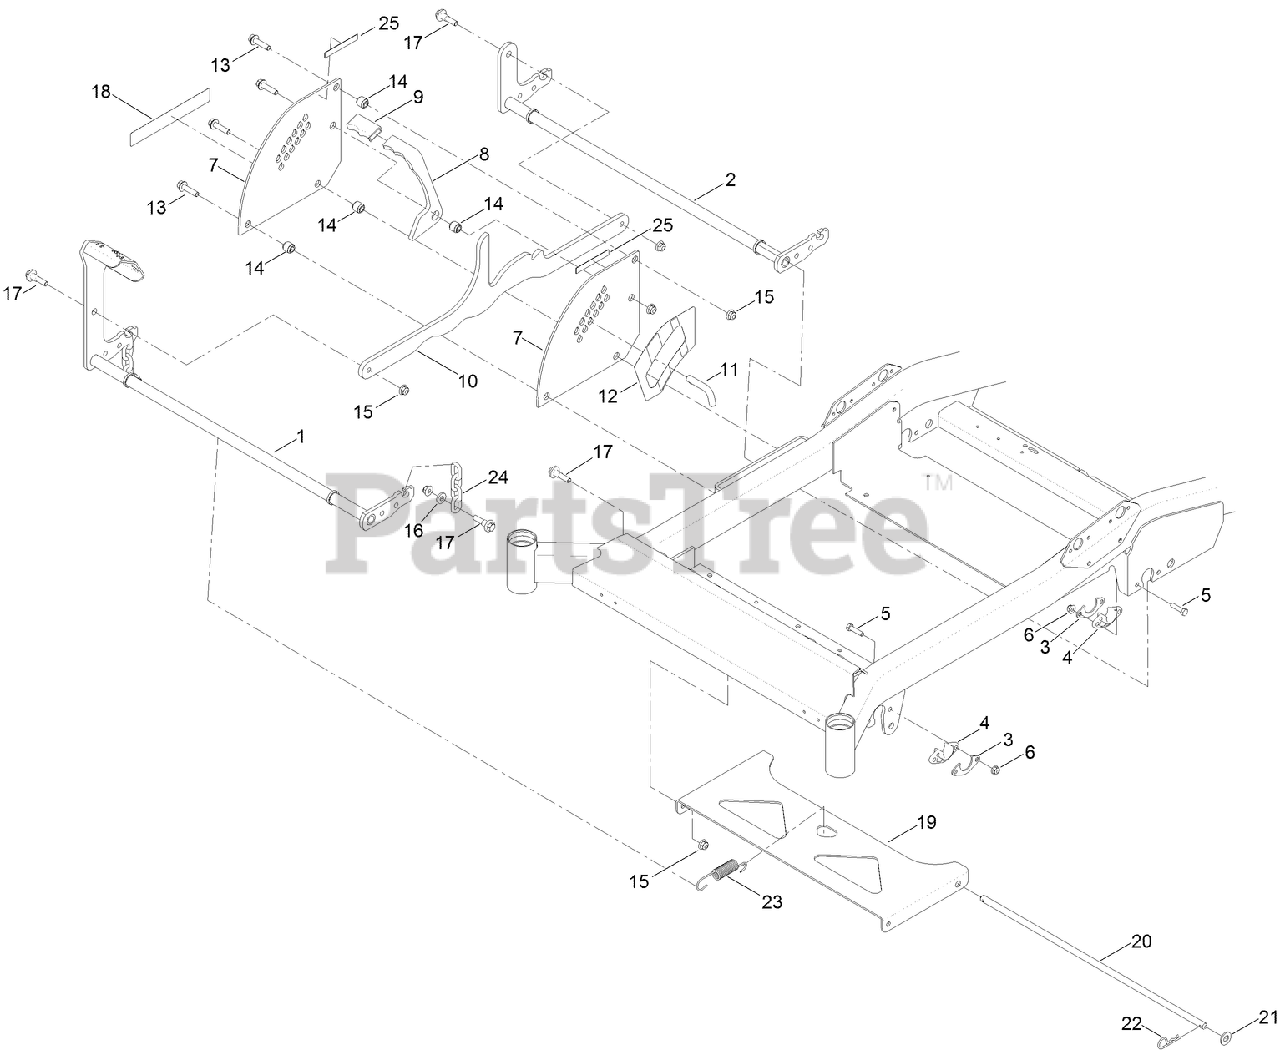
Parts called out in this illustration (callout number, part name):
1	PIVOT-FRONT
2	PIVOT-REAR
3	GUSSET-LIFT, DECK
4	BUSHING-FLANGE
5	SCREW-HH
6	NUT-HF, NI
7	PLATE-DECK, LIFT
8	LOCK-TRANSPORT, HOC
9	GRIP-FLAT
10	LINK-HOC
11	PIN-HOC
12	DECAL-HOC
13	SCREW-HHF
14	SPACER-STEP, DOUBLE
15	NUT-HF, NI
16	SPACER
17	BOLT-SHOULDER
19	PAN-DECK, PIVOT
20	ROD-DECK, PIVOT
21	WASHER-FLAT
22	PIN-COTTER
23	SPRING-EXTENSION
24	CHAIN-DECKLIFT
25	PAD-RUBBER
